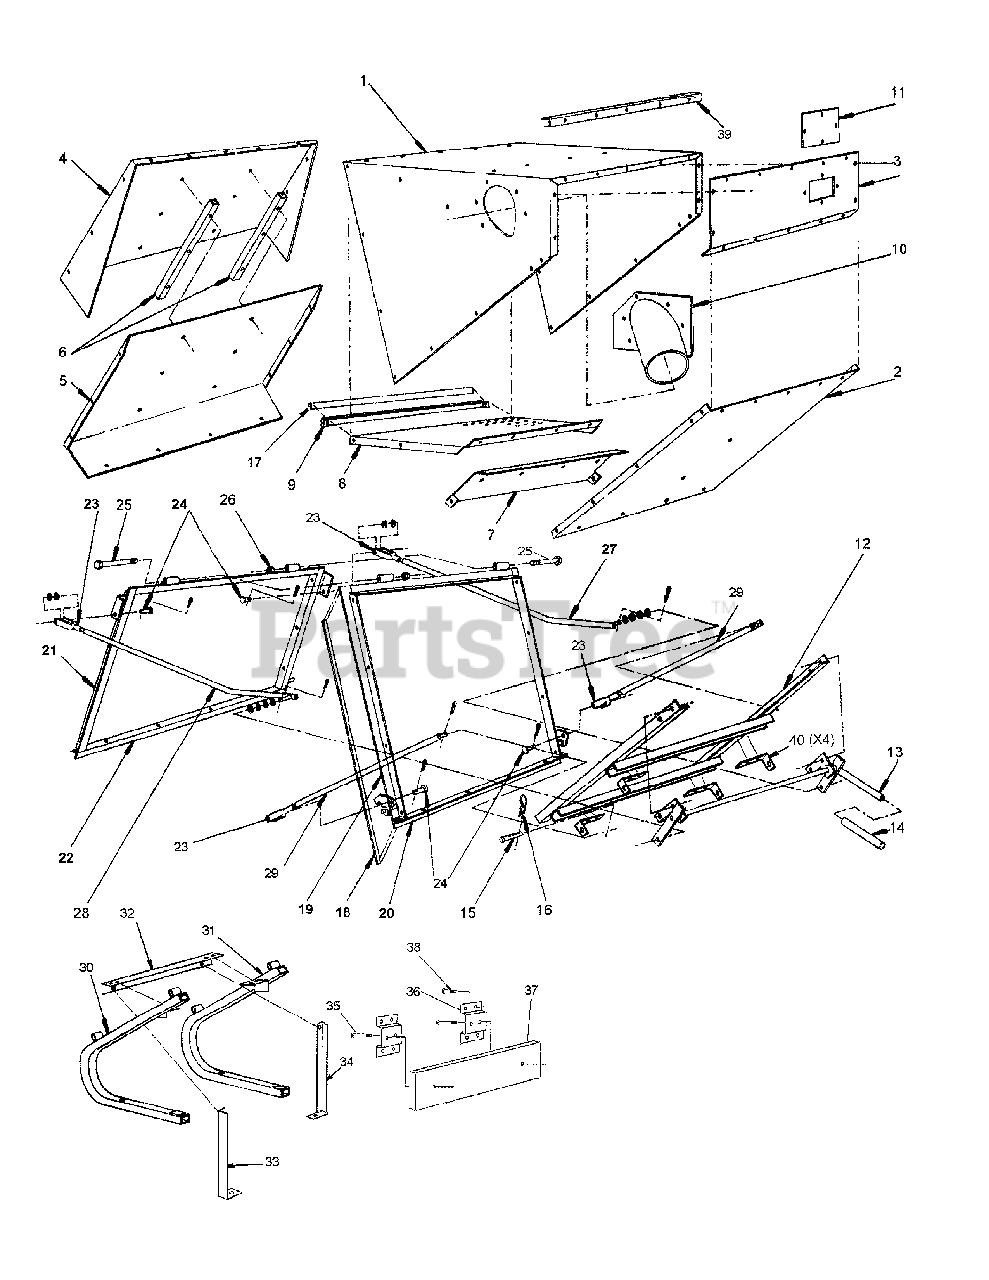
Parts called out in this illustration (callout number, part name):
1	Catcher Body
2	Catch Box Bottom
4	Outer Door Shell
5	Inner Door Shell
6	Door Vent Tubing
7	Intake Deflector
9	Rear Screen Support
10	6" Intake Tube
11	5" x 6.5" Acrylic
12	Catcher Frame Base
13	Lever Dump Assembly
14	5" Vinyl Grip
15	1/2" x 3" Adjustable Clevis
16	0.091" x 2" Hair Spring Cotter
17	Rubber Seals
19	Catcher Opening Frame
20	Bottom Catcher Opening Frame
21	Catcher Door Frame
22	Bottom Door Frame
23	3/8"-24 Adjustable Yoke End
24	3/8" x 1 Clevis Pin
25	1/2" x 5" Hex Head Bolt
26	1/2" Nylock Nut
27	Left Hinge Rod
28	Right Hinge Rod
30	Right Catcher Mounting Frame
31	Left Catcher Mounting Frame
32	Catcher Mounting Frame Bumper
33	Right Catcher Frame Support
34	Left Catcher Frame Support
35	3/8" -16 x 4 1/2" Hex Head
36	Weight Mounting Bracket
37	Weight Bar
38	5/16"-18 x 1" Carriage Bolt
39	Front Bumper
40	Base Frame Tab Adjustable
